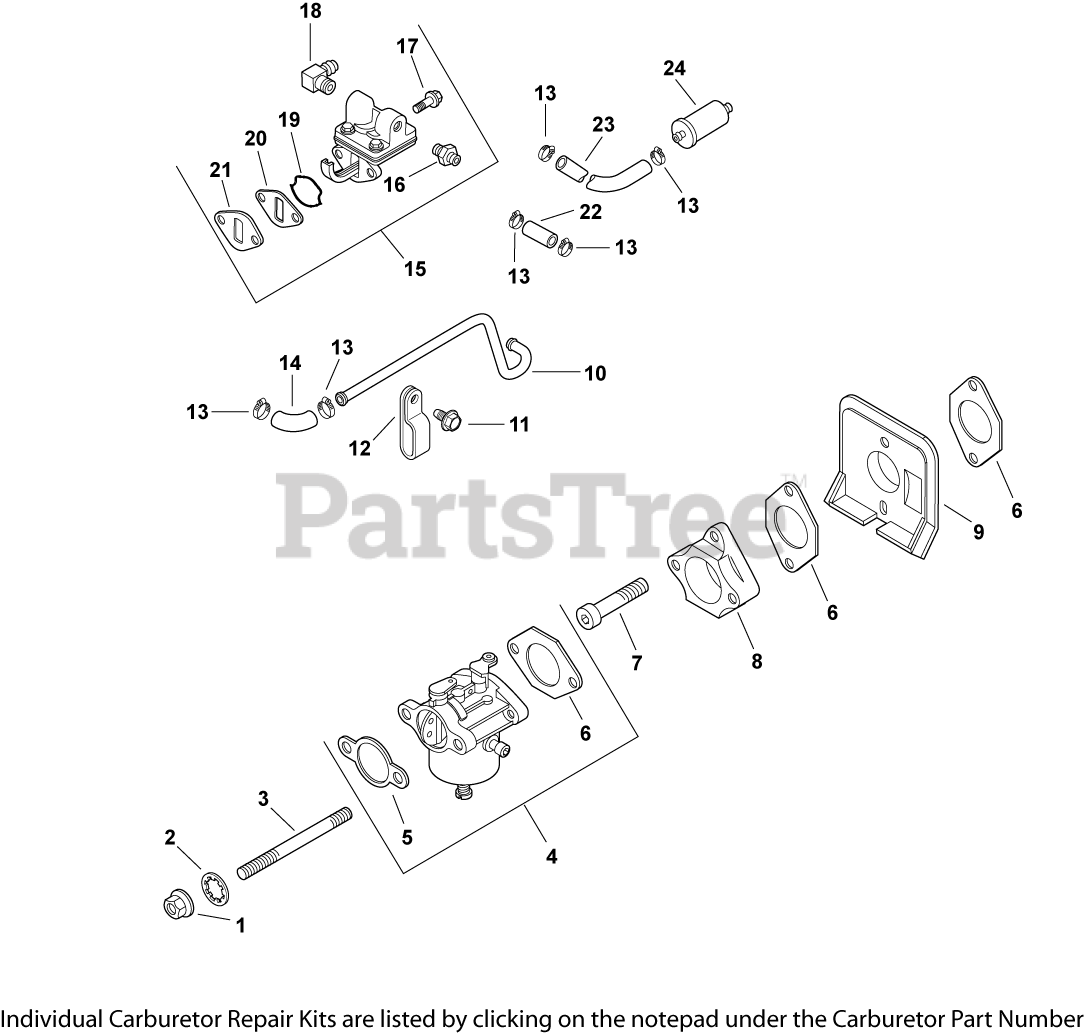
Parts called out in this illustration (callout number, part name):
1	NUT, FLG M6X1.0
2	WASHER, INT TOOTH LOCK 1/4"
3	STUD,M6X1.0X116
4	KIT, CARBURETOR
5	GASKET, AIR CLEANER BASE
6	GASKET, CARBURETOR
7	SCREW, SKT CAP M6X1.0X35
8	ADAPTER, CARBURETOR
9	DEFLECTOR, HEAT
10	LINE, FUEL - DISCONTINUED
11	SCREW, FLG THD FRM M5X.8X10
13	CLAMP, HOSE (KM)-USE 25 237 31-S
14	HOSE, FUEL LOW-PERMEATION
15	KIT, FUEL PUMP
16	KIT, STRAIGHT FITTING
17	SCREW,FLG THD FRM M6X1.0X20-(#25086396S)
18	CONNECTOR, 90 DEG. HOSE
19	O-RING, FUEL PUMP
20	SPACER, FUEL PUMP
21	GASKET, FUEL PUMP
22	LINE - DISCONTINUED
23	LINE - DISCONTINUED
24	FILTER, FUEL
